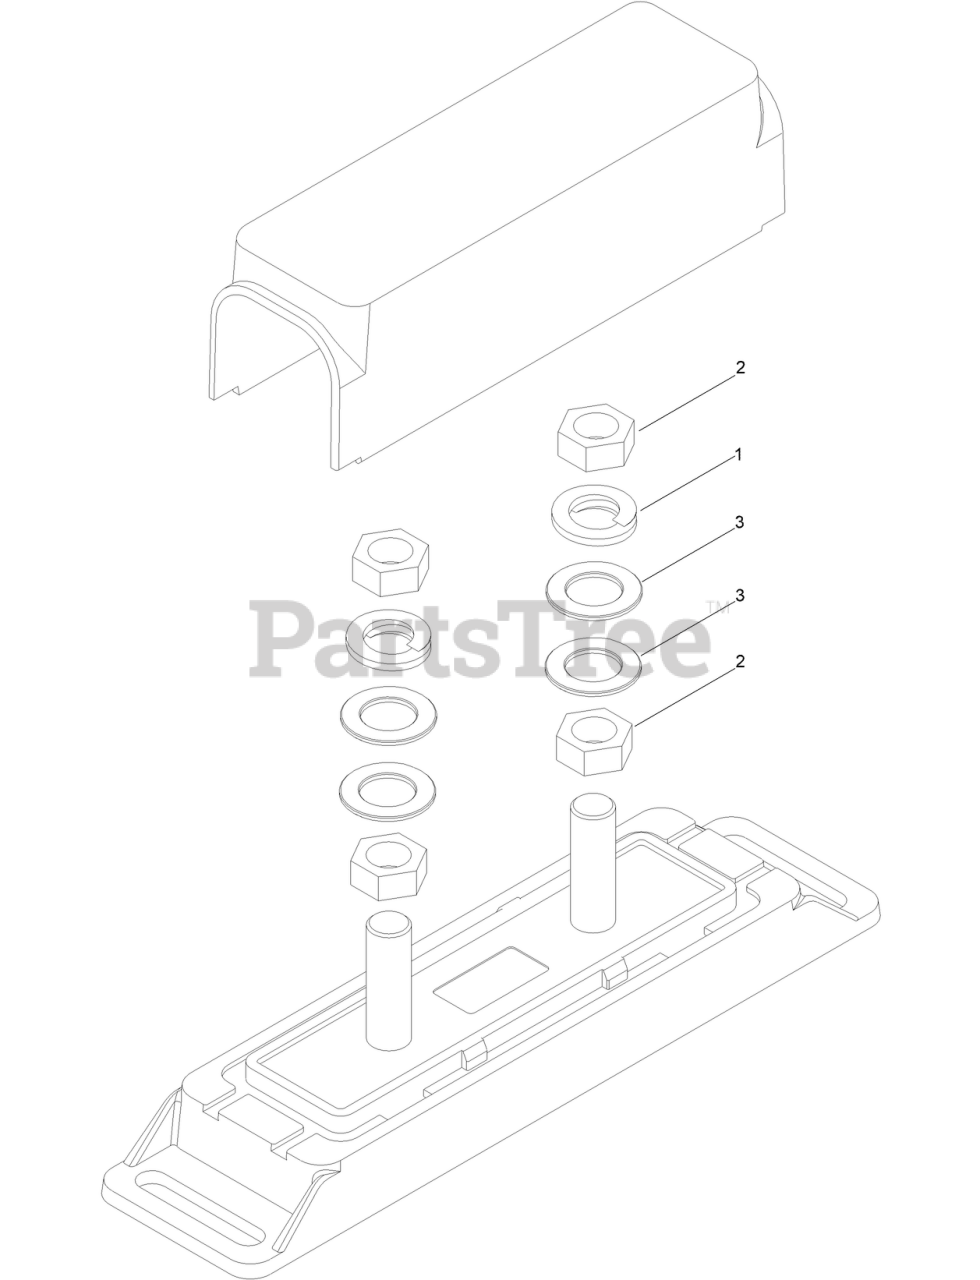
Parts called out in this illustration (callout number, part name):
1	WASHER-LOCK
2	WASHER-FLAT
3	NUT-HEX
